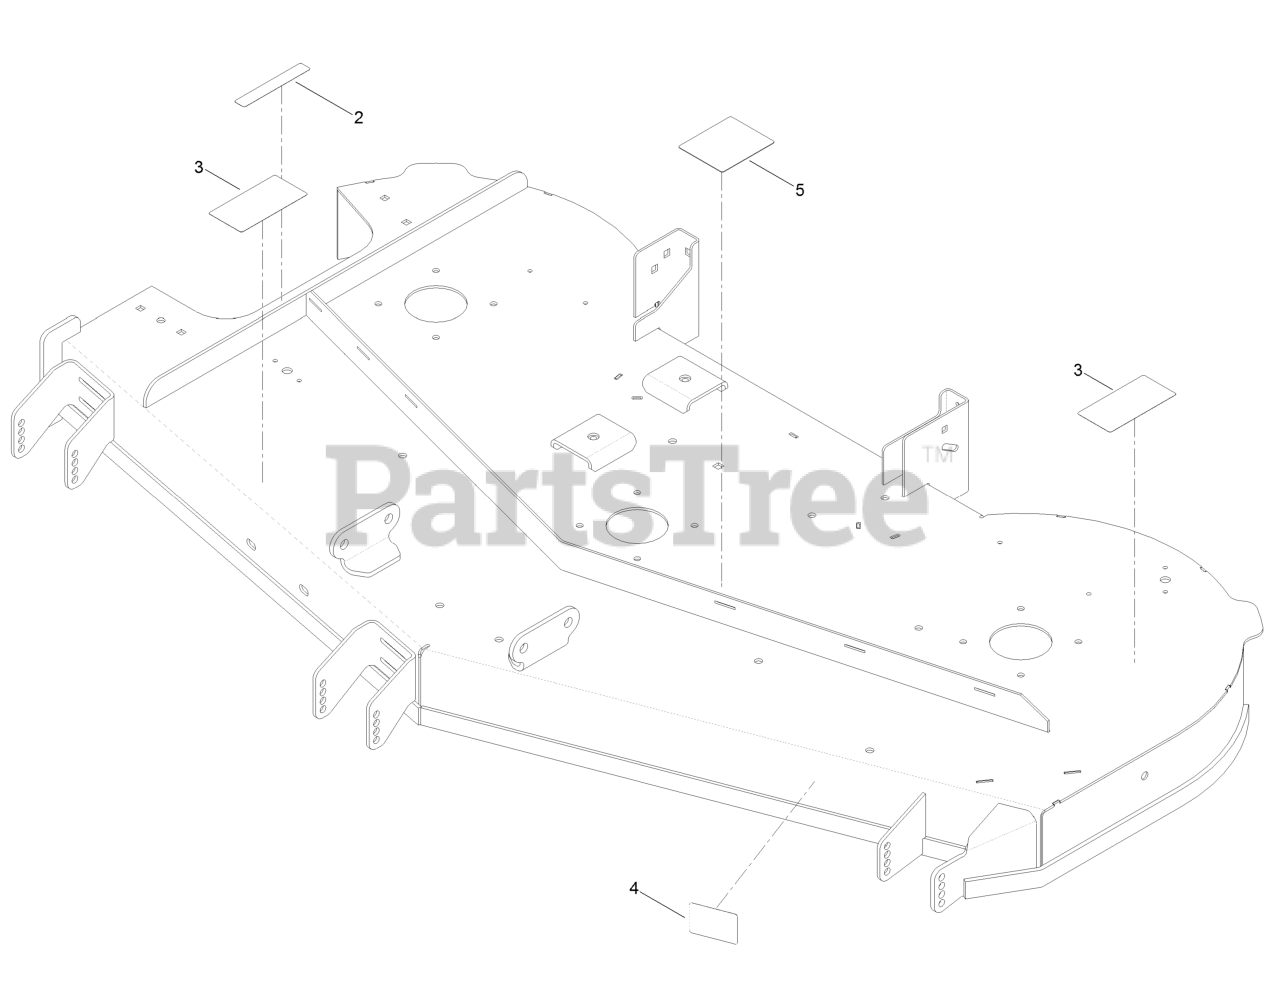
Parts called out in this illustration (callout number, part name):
2	DECAL-DANGER
3	DECAL-DANGER, DECK
4	DECAL-SCALP, ANTI
5	DECAL-ROUTING, BELT
